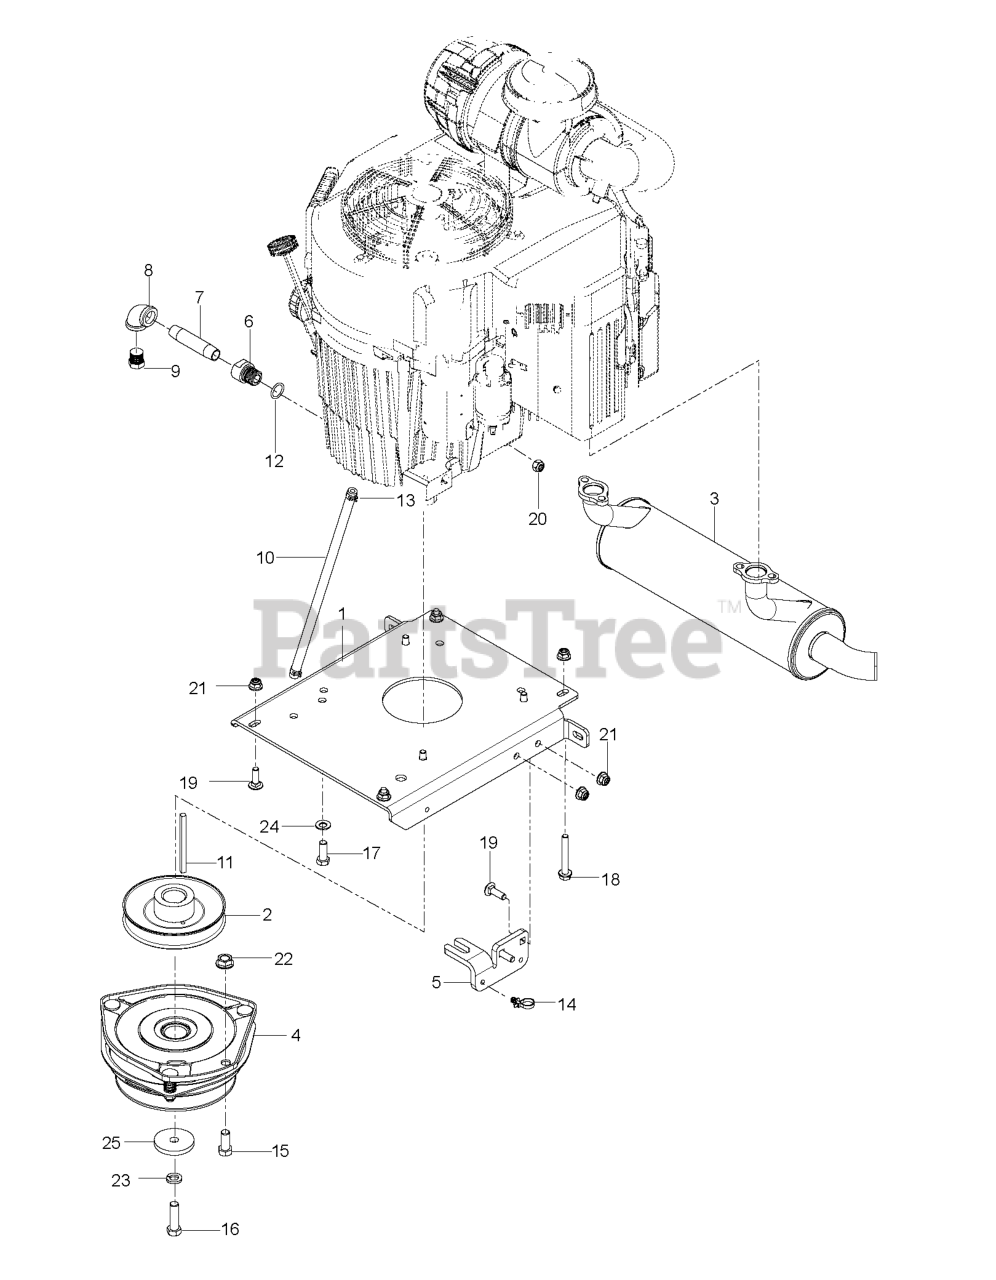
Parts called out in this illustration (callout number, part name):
1	PLATE.ENGINE.BLACK
2	PULLEY, ENGINE
3	MUFFLER, 29HP KAW FX751V-850V
4	CLUTCH, GT3.5
5	STOP, CLUTCH, OGURA
6	ADAPTER, OIL DRAIN
7	PIPE NIPPLE 3/8 X 3
8	90 DEG.ELBOW 3/8NPT
9	PLUG, DRAIN 3/8 NPTF
10	HOSE.1/4".LOW.PERM.FUEL.LN.14"
11	KEY, 1/4 SQ X 3.5
13	HOSE CLAMP
14	TIE WRAP, 8-3/8", W/CLIP
15	BOLT FIN HEX 7/16-14 X 1
16	CLUTCH BOLT7/16-20X1.5GR5.96HR
17	BOLT 3/8-16X1-1/8
18	HHFS 5/16-18 X 2.25 GD 5
19	BOLT
20	NUT M8-1.25 TOP NYL GR10 ZD
21	5/16-18 NYLOC FLANGE NUT
22	NUT 7/16C WHIZ
23	WASHER 7/16 LOCK
24	WASHER, 3/8 DISC SPRING SPEC
25	BLADE WASHER
